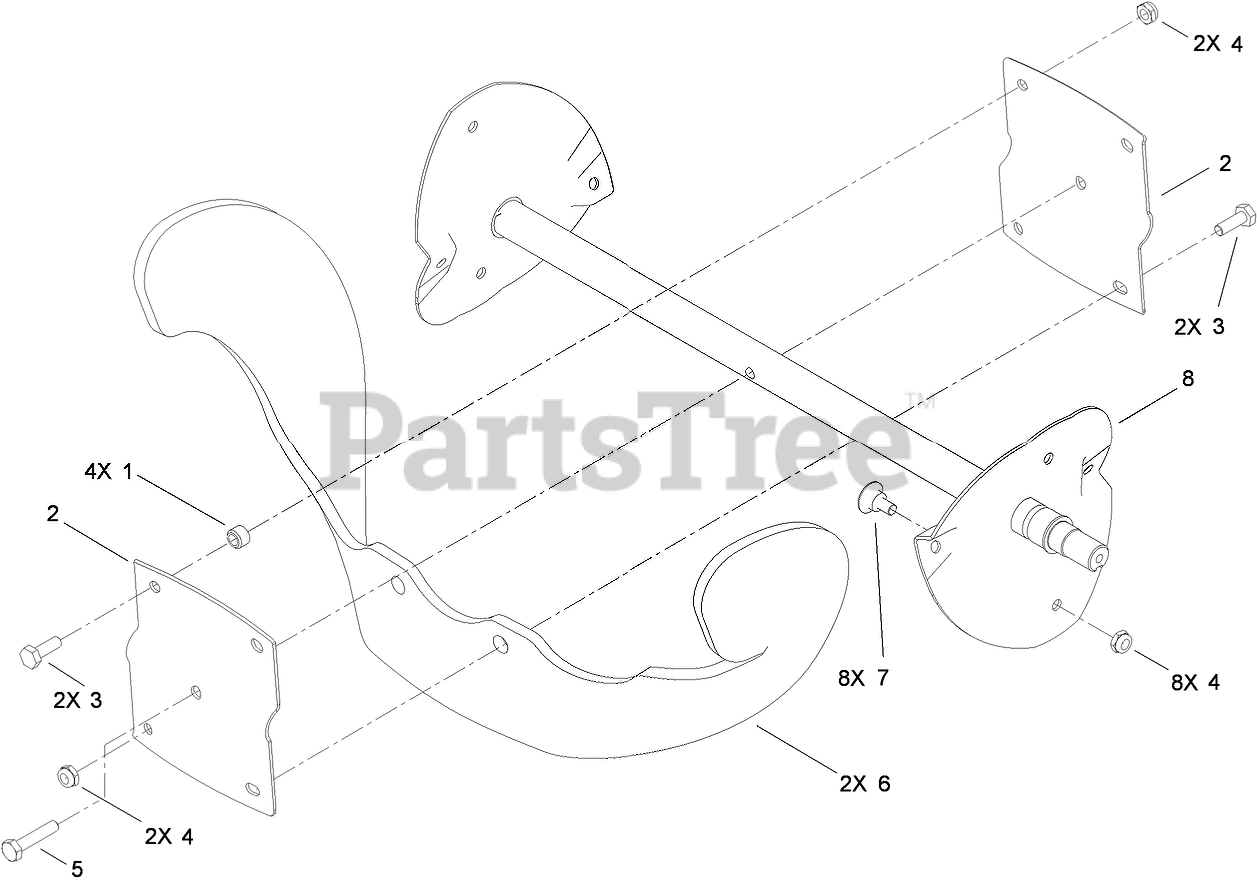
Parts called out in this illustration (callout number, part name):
1	SPACER-BLADE, ROTOR
2	HALF-ROTOR
3	SCREW-HH
4	NUT-LOCK, NI
5	SCREW-HH
6	BLADE-ROTOR
7	SCREW
8	ROTOR
